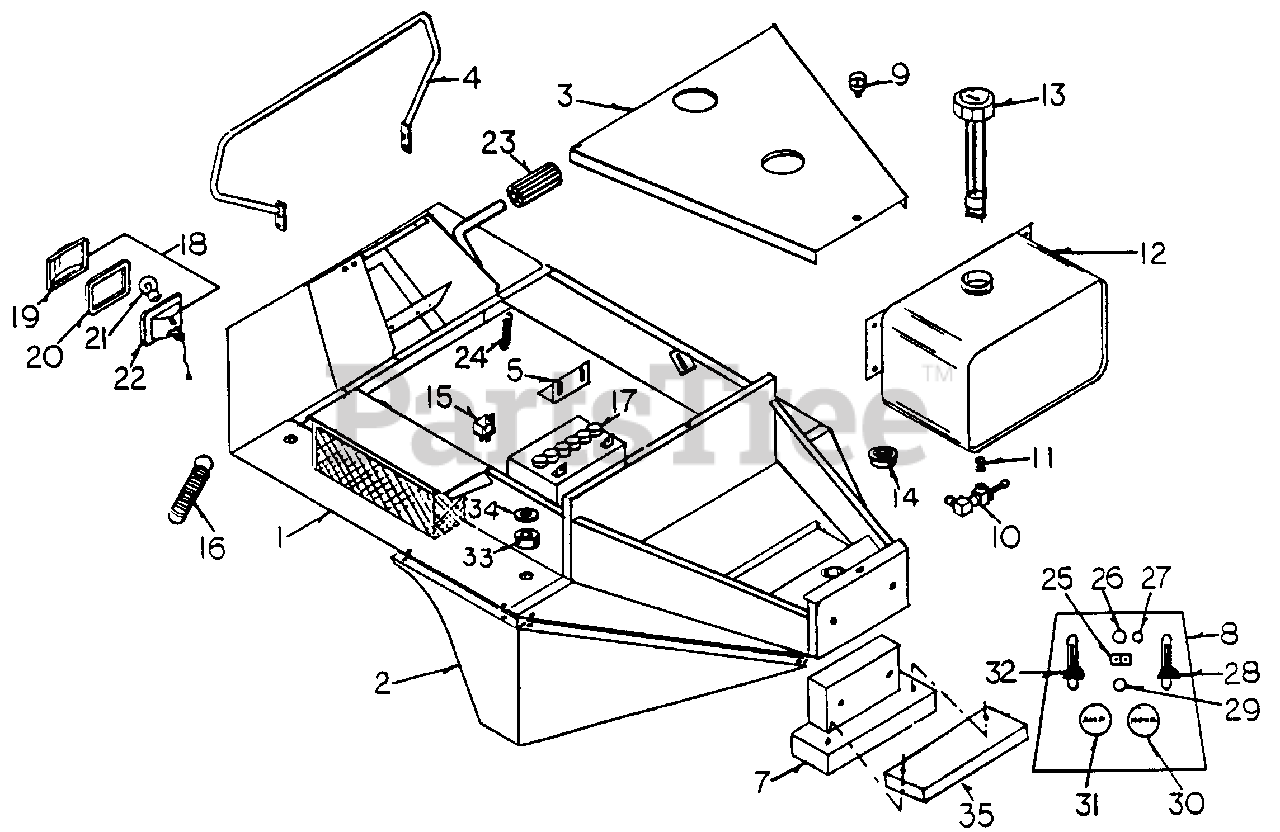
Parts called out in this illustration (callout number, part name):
2	Fender, LH
13	Fuel Tank Cap w/Gauge
15	Relay
17	Battery
18	Light Aggembly
19	Leng
20	Gasket
21	Bulb
23	Brake Pedal Pad
25	Light Swltch
26	Clutch Switch
28	Throttle Cable
29	Ignition Swltch
33	Rubber Body Mbunt
34	Body Mount Washer
35	Tall Welght, 13 lb.
